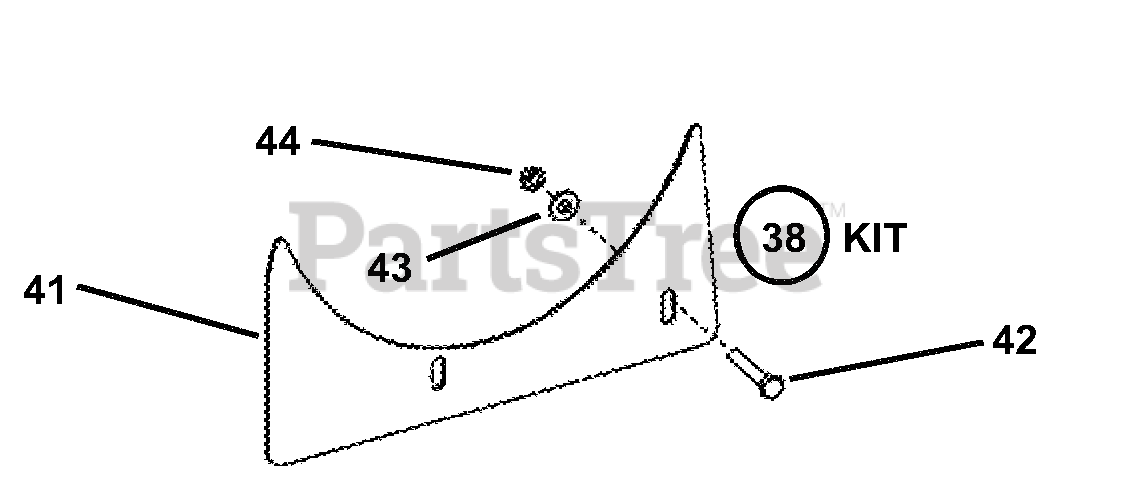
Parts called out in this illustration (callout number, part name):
38	WASHER, 3/8" Split Lock
41	SHIELD, Debris
42	BOLT, 1/4-20 x 1-1/2" Hex
43	WASHER, 1/4" Flat
44	NUT, 1/4-20 Hex Top Lock
